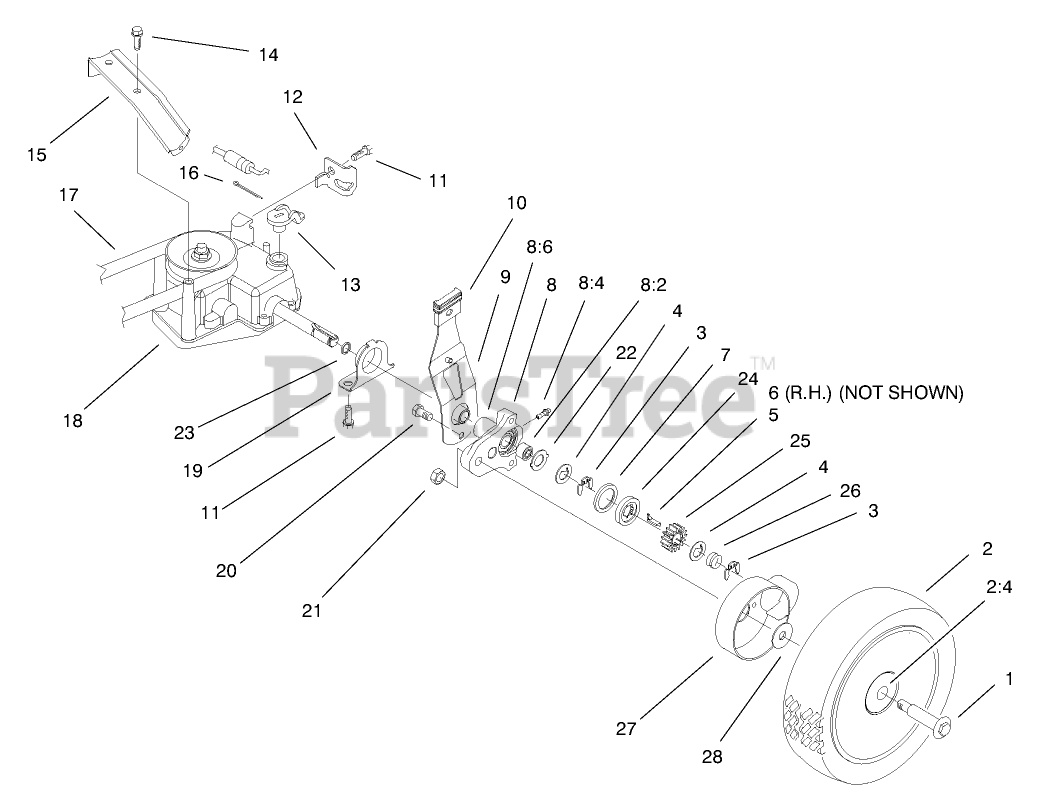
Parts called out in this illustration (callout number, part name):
1	BOLT-SHOULDER
2	WHEEL TIRE ASM (SP)
2:4	BUSHING
3	RING-RETAINING,CLIP
4	WASHER-THRUST, KEYED
5	KEY-ROCKING, LH
6	KEY-ROCKING, RH
7	RING-FRICTION
8	PIVOT ARM ASM
8:4	FITTING-GREASE
8:6	BUSHING
9	SPRING ARM ASM
10	KNOB-ARM
11	SCREW-HWHTF
12	RETAINER-CABLE
13	LEVER-SHIFT
14	SCREW-HWHTF
16	PIN-COTTER
17	V-BELT
18	GEARCASE ASM
19	CAP-END
20	SCREW-HSH, THREAD FORMING
21	LOCKNUT
22	WASHER-ARM, PIVOT
23	O-RING
24	WASHER-CLUTCH
25	GEAR-PINION
26	SPRING-COMPRESSION
27	COVER-WHEEL
28	SPACER-COVER, WHEEL
